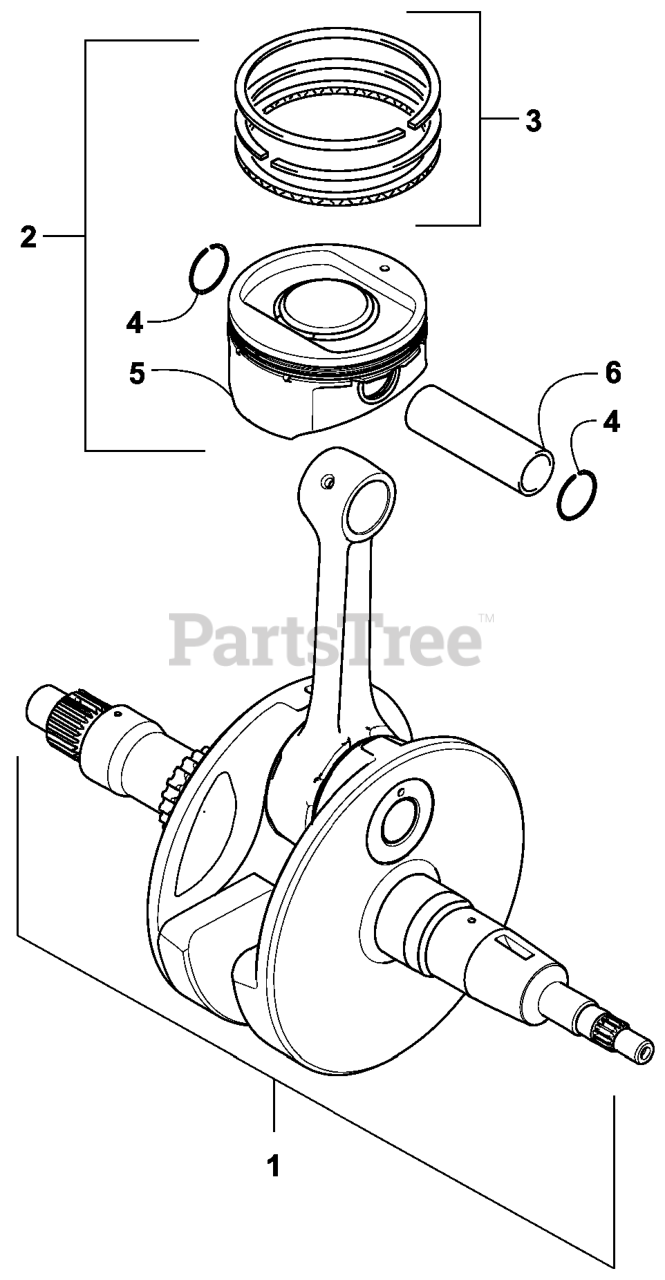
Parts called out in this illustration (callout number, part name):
2	PISTON SET
3	PISTON RING SET
4	CIRCLIP-PISTON PIN
5	Piston
6	PIN-PISTON
